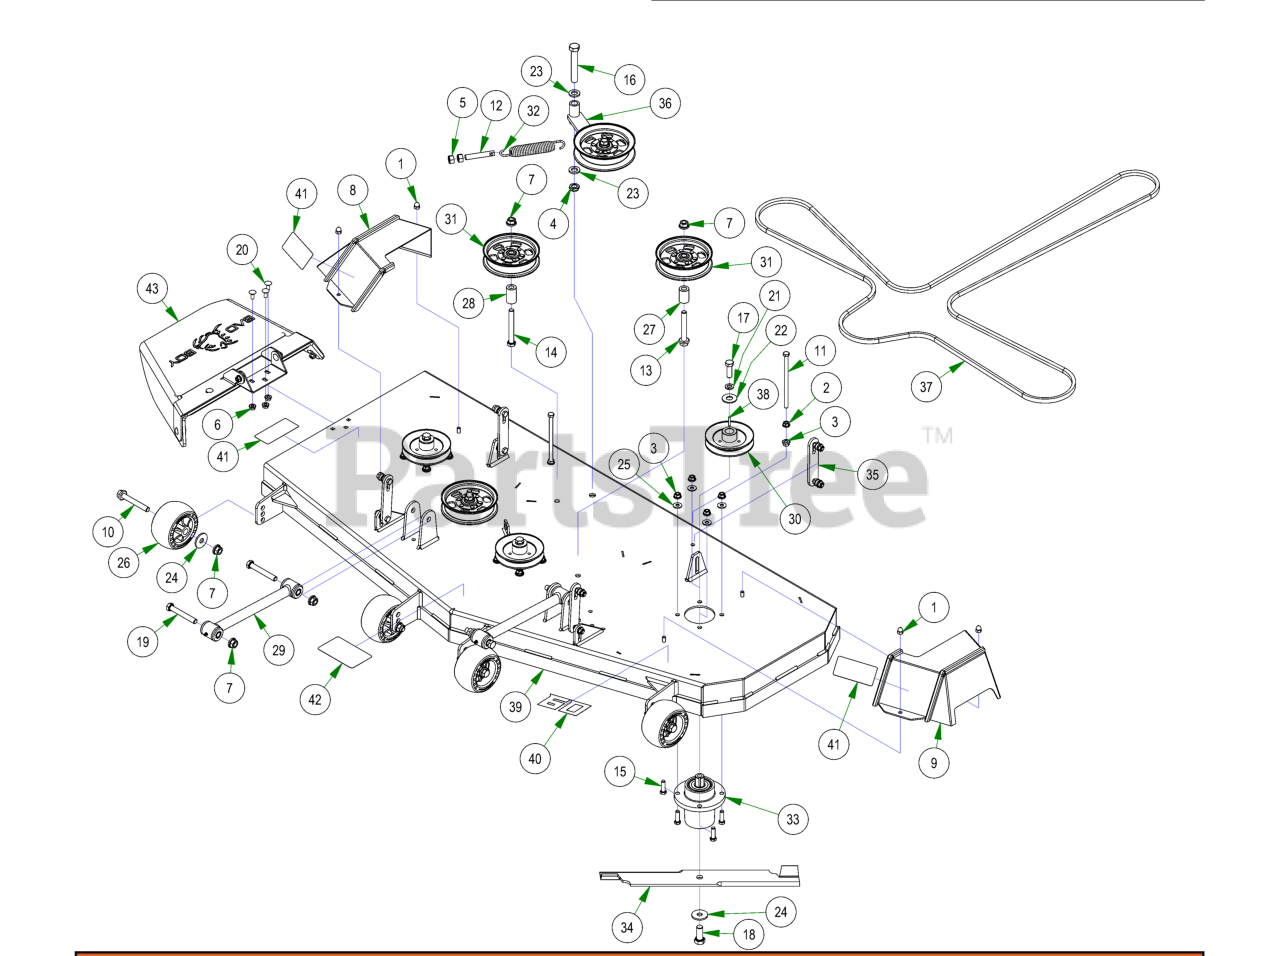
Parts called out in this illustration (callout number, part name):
1	5/16-18 ACORN NUT HIGH-CROWN ZC
2	3/8-16 HEX SERRATED FLANGE NUT HARD/ZINC
3	3/8-16 NYLON INSERT FLANGE LOCKNUT (GR.F) ZINC
4	5/8-11 NYLON INSERT JAM LOCKNUT ZINC
5	1/2-13 HEX NUT ZINC
6	5/16-18 NYLON INSERT FLANGE LOCKNUT ZINC
7	1/2-13 NYLON INSERT FLANGE LOCKNUT ZINC
8	2021 Maverick 54”/60” RH Pulley Cover
9	2021 Maverick 54”/60” LH Pulley Cover
10	1/2-13 X 90MM HEX FLANGE BOLT W/SHOULDER (GR.8) ZINC
11	3/8-16 X 6.5 HEX CAP SCREW (GR.5) ZINC
12	All Thread
13	1/2-13 X 3-1/2 HEX FLANGE BOLT (GR.8) ZINC
14	1/2-13 X 4 HEX CAP SCREW (GR.8) ZINC YELLOW
15	3/8-16 X 1-1/4 HEX CAP SCREW (GR.5) ZINC
16	5/8-11 X 4 HEX CAP SCREW (GR.8) ZINC YELLOW
17	1/2-20 X 1-1/2 HEX CAP SCREW (GR.5) ZINC
18	5/8-18 X 1-1/2 HEX CAP SCREW (GR.8) ZINC YELLOW
19	1/2-13 X 3-1/2 HEX CAP SCREW (GR.5) ZINC
20	5/16-18 x 3/4 Carriage Bolt
21	1/2 SPLIT LOCKWASHER (GR.8) ZINC/YELLOW
22	5/8 USS FLAT WASHER (1-3/4" OD) GR.8 ZINC YELLOW
23	.635 ID X 1.120 OD X .140 THICK FLAT WASHER NYLON
24	1/2 BELLEVILLE WASHER (1-5/8 OD X .140 THK) ZINC
25	5/16 USS FLAT WASHER (7/8 OD) ZINC
26	Deck Wheel
27	.502 ID X .750 OD X 1.500 Long Spacer
28	1 3/4" Pulley Spacer
29	Hybrid Turnbuckle/Deck Locator
30	60" MZ Deck Pulley (Representation Only)
31	5-3/4 Idler Pulley
32	Deck Idler Spring
33	Spindle Assembly-MZ
34	60" High Lift Fusion Blade
35	Deck Hanger Assembly
36	2017 MZ/ZT Deck Idler Assembly
38	3/16 X 1 SQ MACHINERY KEY 1018 STL ZINC
39	2023 60" x 4" Deck
40	60" Deck Decal
41	Danger Decal-Spindle/Discharge
42	Deck Belt Route Decal
43	MZ Discharge Chute Assembly
